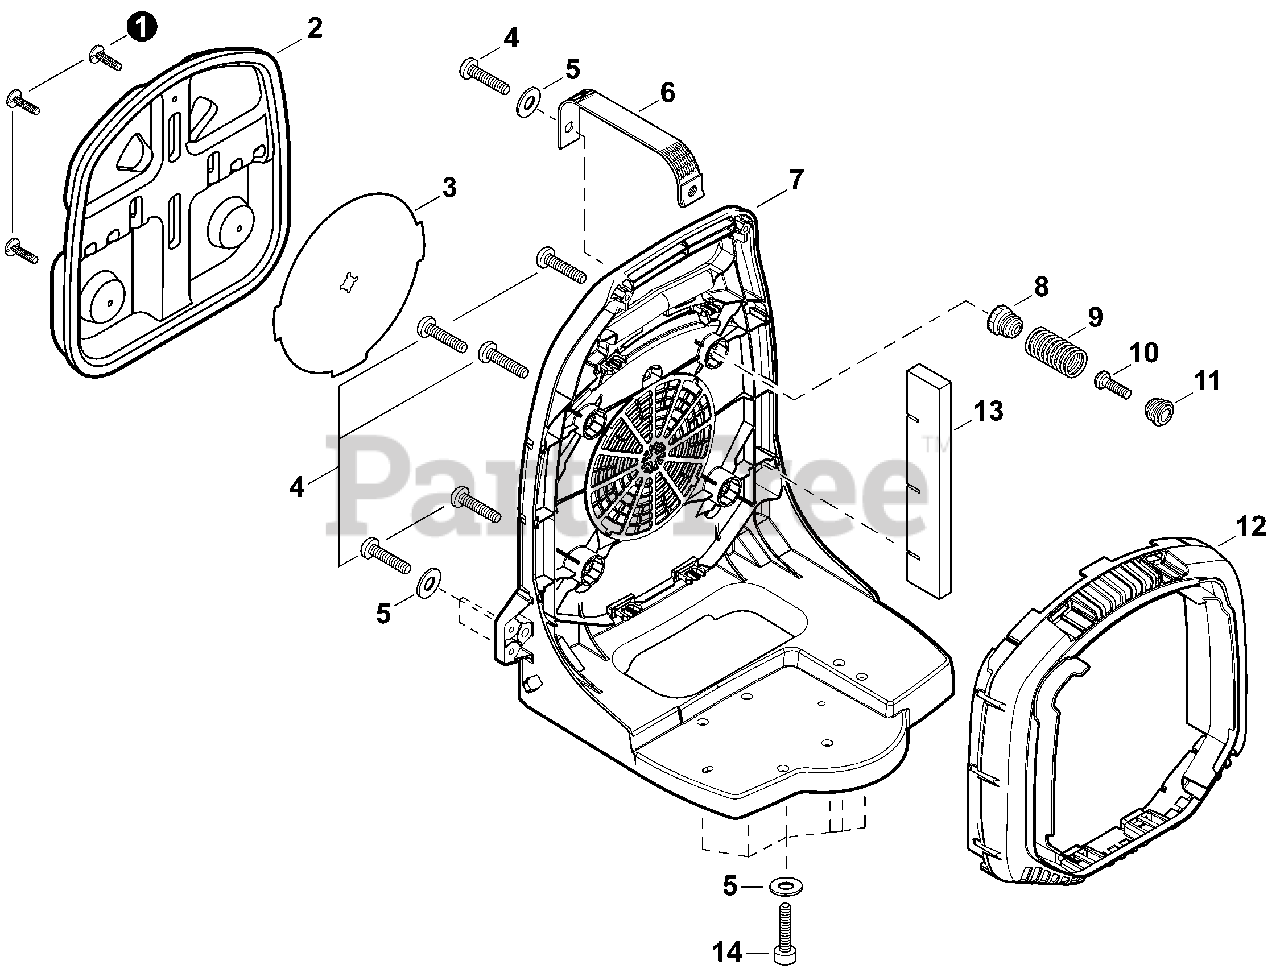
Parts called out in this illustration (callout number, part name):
2	CUSHION, BACKPACK
3	INSERT, COLD WEATHER
4	BOLT, TORX 5×20
5	WASHER 5.5×16×2T
6	STRAP, SAFETY 1.2×100
7	FRAME, BACKPACK
8	HOLDER, SPRING
9	SPRING, COMPRESSION
10	BOLT, TORX 5×16
11	HOLDER, SPRING
12	GUARD, DEBRIS
13	PAD, FOAM
14	SCREW 5×25
